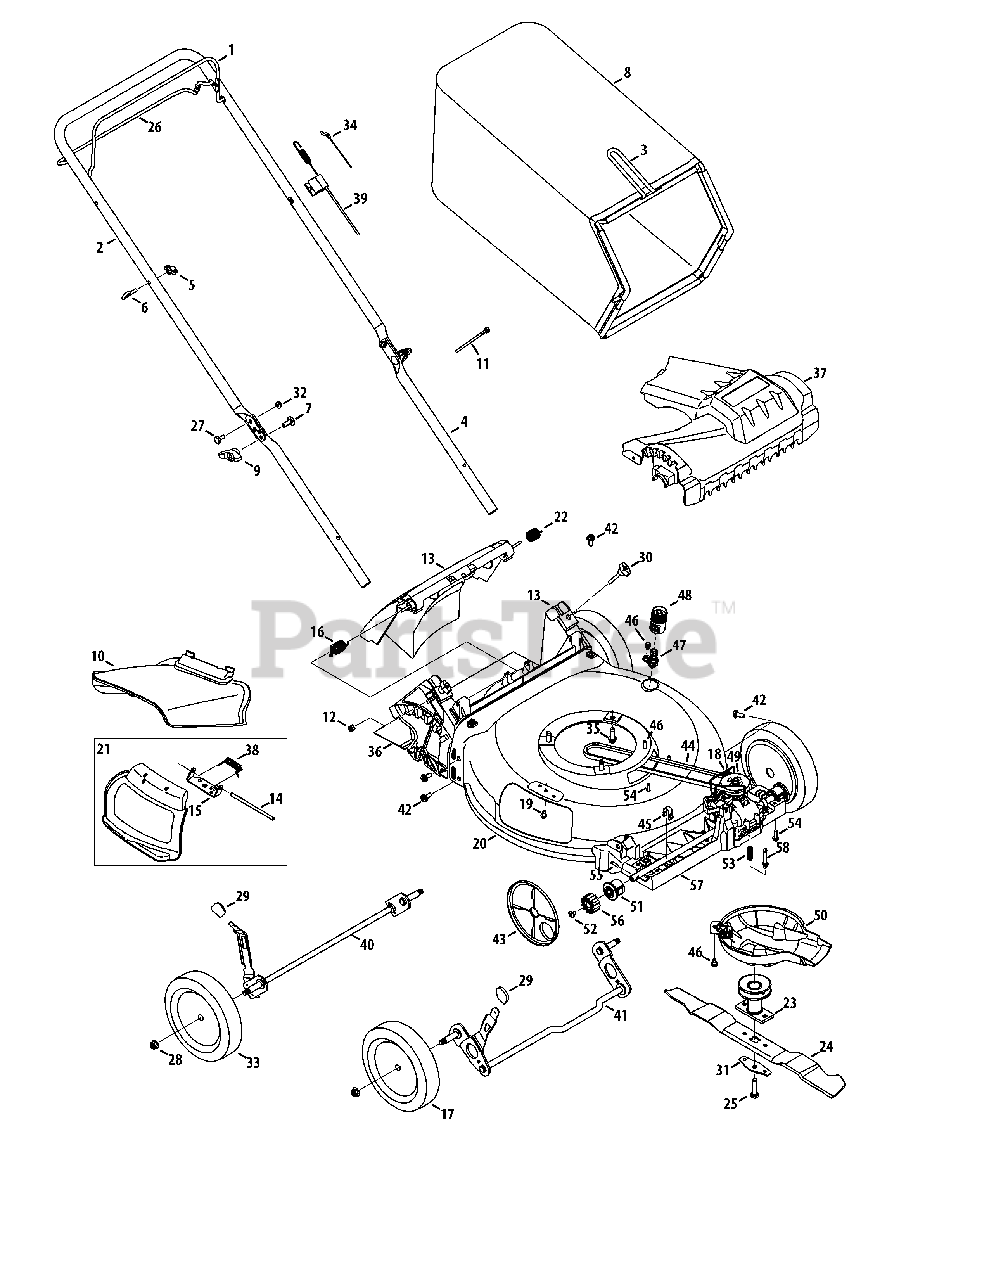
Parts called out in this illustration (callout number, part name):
1	Blade Control
2	Upper Handle
3	Grass Catcher Frame
4	Lower Handle
6	Rope Guide
7	Carriage Screw ,5/16-18
8	Grass Bag
10	Side Chute
11	Cable Tie
12	Nut, Sq., 1/4-20
13	Rear Discharge Door Assembly
13	Rear Discharge Door Assembly - (Lowes 766)
15	Chute Deflector Bracket
16	Torsion Spring - RH
17	Front Wheel
18	Transmission Wire
19	Screw, 1/4-20 x .500
20	Deck , 21"
21	Hinged Mulch Plug Assembly
22	Torsion Spring - LH
23	Blade Adapter Assembly
24	Mulching Blade
25	Screw , 3/8-24 x 1.50
26	Drive Control
27	Sldr. Screw, .375 x .126 x 1/4-20
28	Flange Lock Nut, 3/8-16
29	Adjustment Lever Knob
30	Wing Nut
31	Blade Bell Support
32	Nut, Flange Lock, 1/4-20
33	Rear Wheel
34	Control Cable
35	TT Sems Screw, 3/8-16 x 1.0
36	Trail Shield
37	Front Cover
38	Torsion Spring
39	Drive Cable
40	Rear Axle Assembly
41	Front Axle Assembly
42	Screw, 5/16-14 x .750
43	Wheel Dust Cover
45	Front Axle Clip
46	Scr., Shldr., 1/4-20 x .50
47	Water Nozzle
48	Water Nozzle Adapter
49	Transmission Assembly
50	Engine Baffle
51	Bearing Assembly
52	Screw, 1/4-20 x .390
53	Compression Spring
54	Screw, 1/4-15 x .750
56	Spur Gear, 14T - RH
56	Spur Gear, 14T - LH
57	Lower Tray
58	Spring Body
